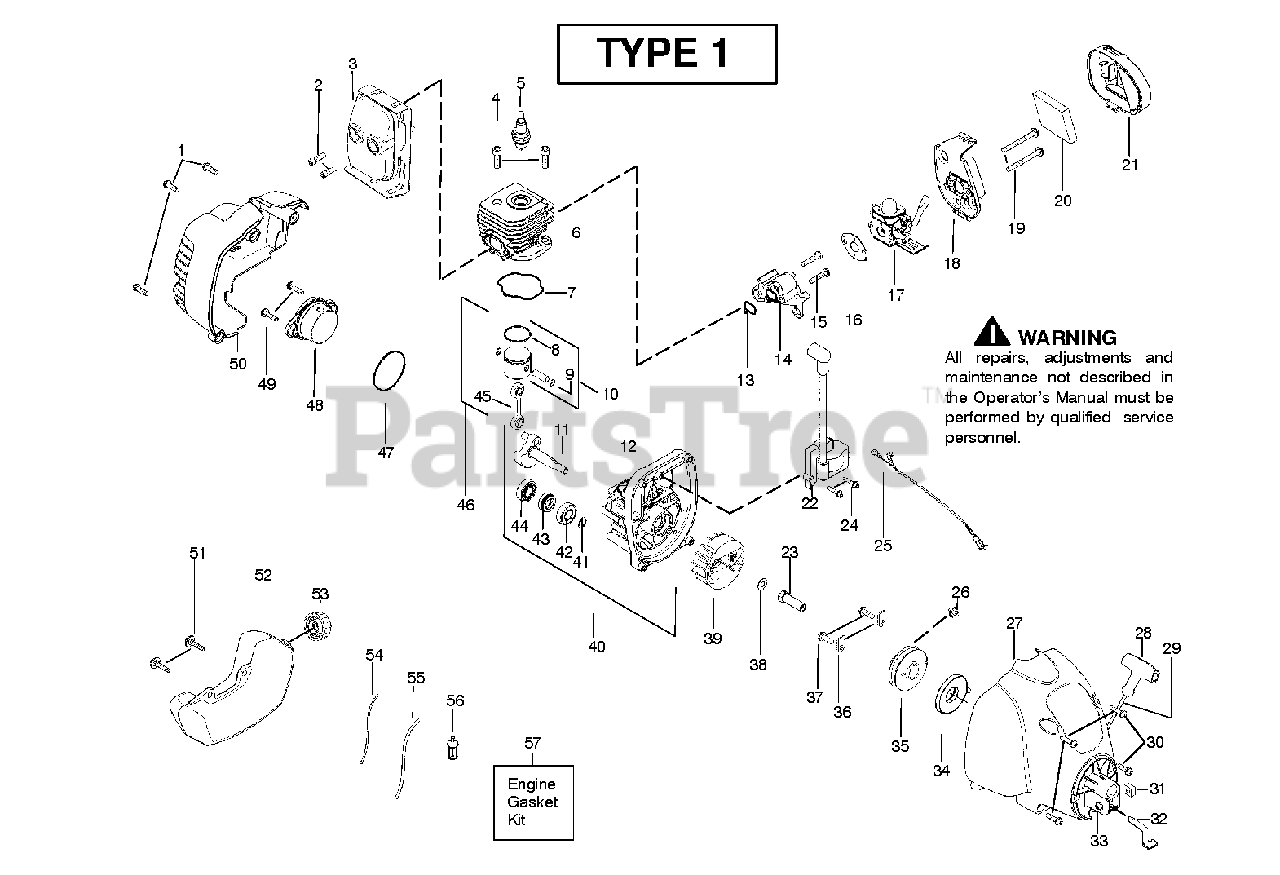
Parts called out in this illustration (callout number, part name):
2	BOLT MUFFLER
3	ASSEMBLY
5	PLUG-SPARK (RCJ-6Y)
6	CYLINDER MACHINED 25CC LO
7	KIT GASKET 25CC
8	PISTON RING
9	WRIST PIN RET.
10	PISTON KIT
11	ASSY CRANKSHAFT
12	ASSY CRANKCASE
13	KIT GASKET 25CC
14	ADAPTOR CARBURETOR
16	KIT GASKET 25CC
17	KIT CARB ASSY #C1U-W18
17	KIT CARB ASSY WT 669
18	BASE AIRBOX
20	FOAM AIR FILTER
21	COVER AIR BOX
23	DRIVE-COUPLING
25	CABLE ASSY
26	SCREW SEMS TOOTHED WASHER
28	HANDLE-STARTER
29	KIT ROPE
31	NUT SQUARE
34	STARTER SPRING
35	STARTER PULLEY KIT
36	RETAINER
37	SCREW 8-16 X 9/16 (PLAS
38	WASHER FLAT
39	ASSY FLYWHEEL
40	ASSEMBLY
41	RETAINING RING
42	OUTER BEARING
44	BEARING
45	KIT-CONN ROD ASSY
46	PISTON KIT
47	KIT GASKET 25CC
48	ASSY REAR PLUG
50	CYLINDER COVER
51	SCREW FUEL TANK RETAINER
52	ASSY FUEL TANK
53	CAP ASSY W/ RETAINER
54	KIT-LINE
55	LINE KIT
56	FUEL PICK-UP ASSY
57	KIT GASKET 25CC
